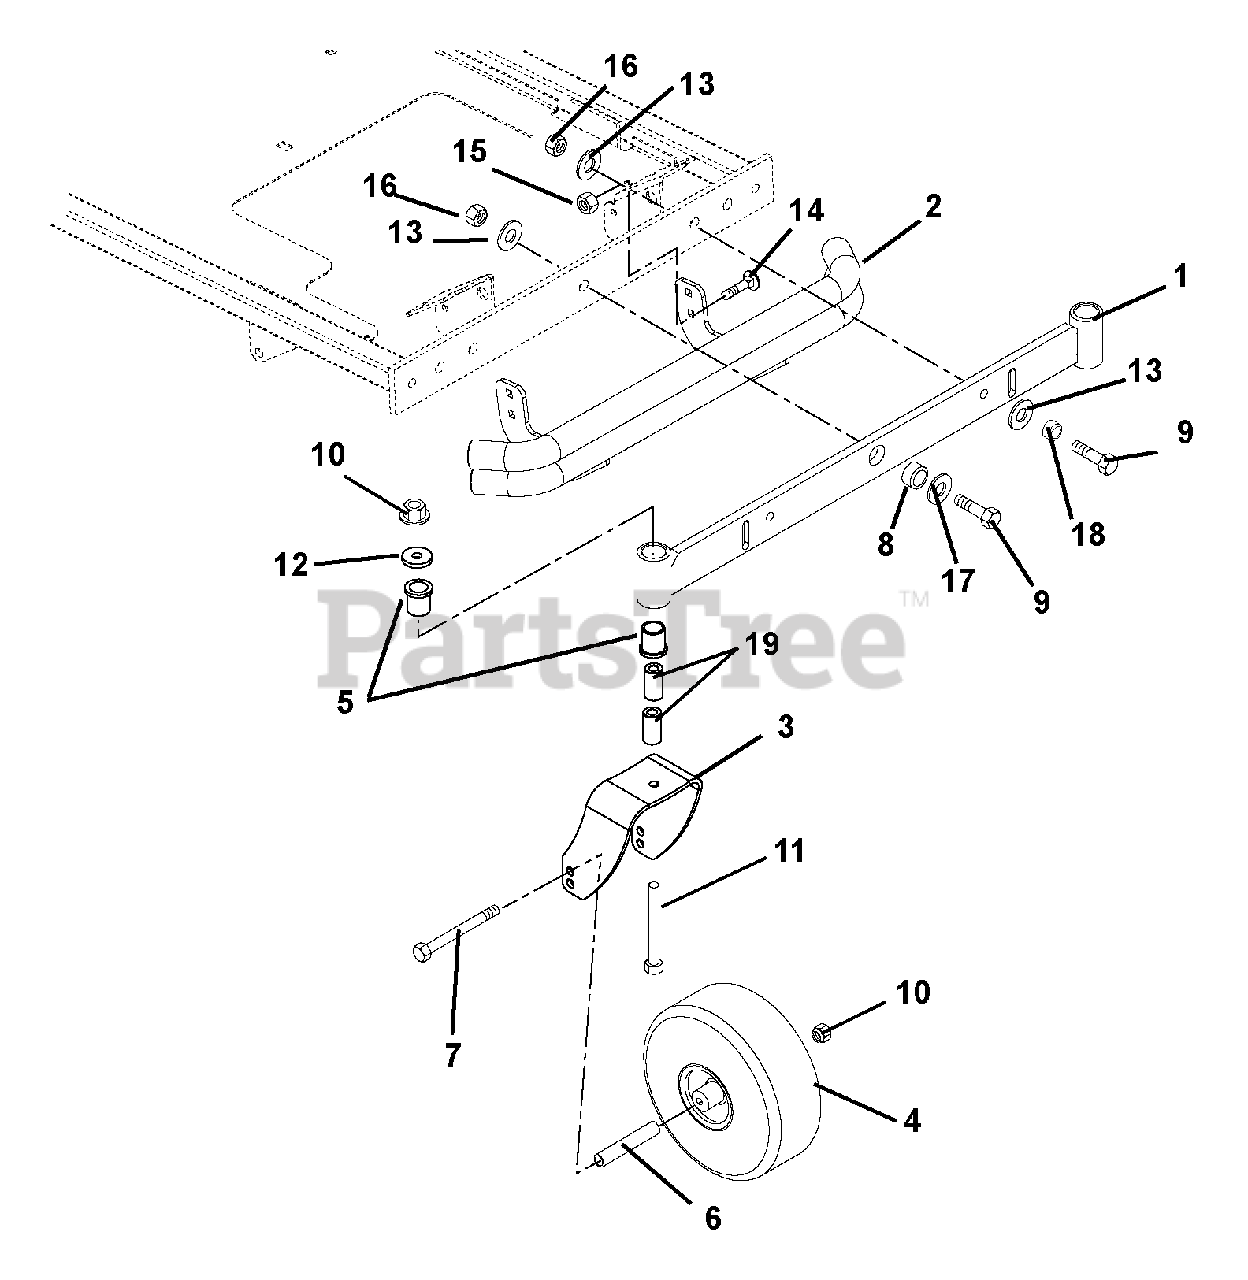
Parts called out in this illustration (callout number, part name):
1	WMT, FRONT AXLE
2	WMT, BUMPER
3	FORK, CASTER- WELDED
4	ASSY-TIRE 4 X 11 - 4 PLY
5	BSHG-FLG 1.00X1.25X1.50X1.50EP
6	SPACER, ROLLED WHEEL
7	@BLT-HEX .50-13X6.50 GR5 YWZC
8	BUSHING, AXLE PIVOT
9	BLT-HEX .62-11X2.25 YWZC GR8
10	@NUT-LK-TOP-FLG .50-13 YWZC
11	@BLT-HEX .50-13X5.00 GR5 YWZC
12	WSHR-FL-STL.511X1.441X.125 YWZ
13	WSHR-FLT .640X1.75X.250 YWZC
14	@BLT-RDHDSQNK .38-16X1.00 G5YZ
15	@NUT-LK-NYL-FLG .38-16 YWZC
16	@NUT-LK-NYL .625-11 YWZC
17	@WSHR-FL-STL.688X1.75X.134 YWZ
18	SPACER, .750 D X .558 LONG
19	SPACER, CASTER .50X1.00X1.84
